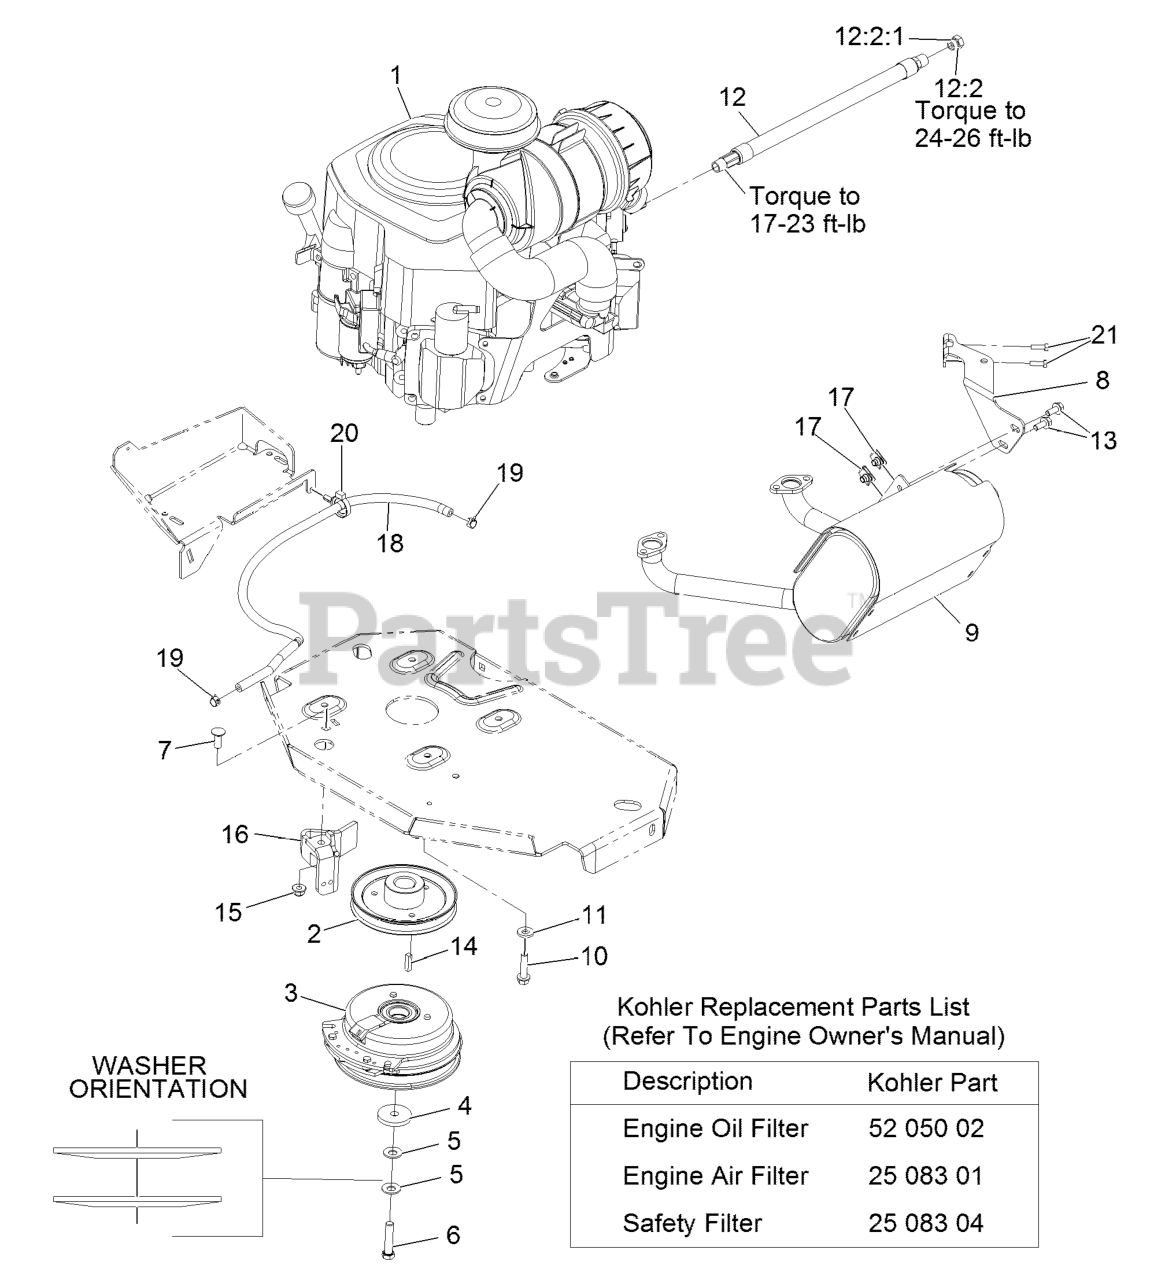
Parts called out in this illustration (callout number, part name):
1	Engine-Kohler
2	SHEAVE
3	CLUTCH KIT
4	WASHER-CLUTCH
5	WASHER-SPRING
6	SCREW-HH W/LOCTITE
7	SCREW-CARR
8	MUFFLER BRACKET KIT
10	SCREW-HWH
11	WASHER-BELLEVILLE
12	OIL DRAIN HOSE ASM
12:2	PLUG-HH
12:2:1	O-RING
13	SCREW-HHF
15	NUT-HF, NI
16	CLUTCH-ANCHOR
18	HOSE-FUEL
19	CLAMP-HOSE
20	CLAMP-HOSE
21	SCREW-HH M6-1 X 20Mm W/Patch
